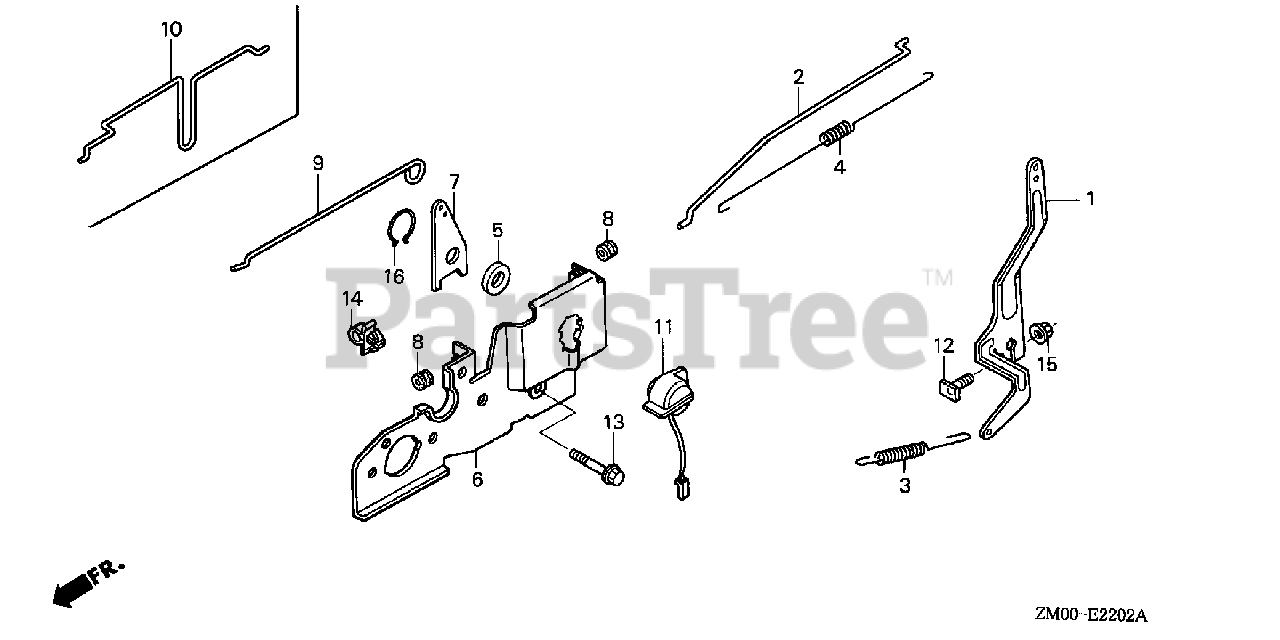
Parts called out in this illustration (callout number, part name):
1	ARM, GOVERNOR
2	ROD, GOVERNOR
3	SPRING, GOVERNOR
4	SPRING, THROTTLE RETURN
6	BASE, CONTROL
8	GROMMET, CHOKE ROD
9	ROD, CHOKE
11	SWITCH ASSY., ENGINE STOP
12	BOLT, GOVERNOR ARM
13	BOLT, FLANGE (6X45)
14	CLIP, CABLE (A)
15	NUT, FLANGE (6MM)
16	CIRCLIP, OUTER (14MM)
